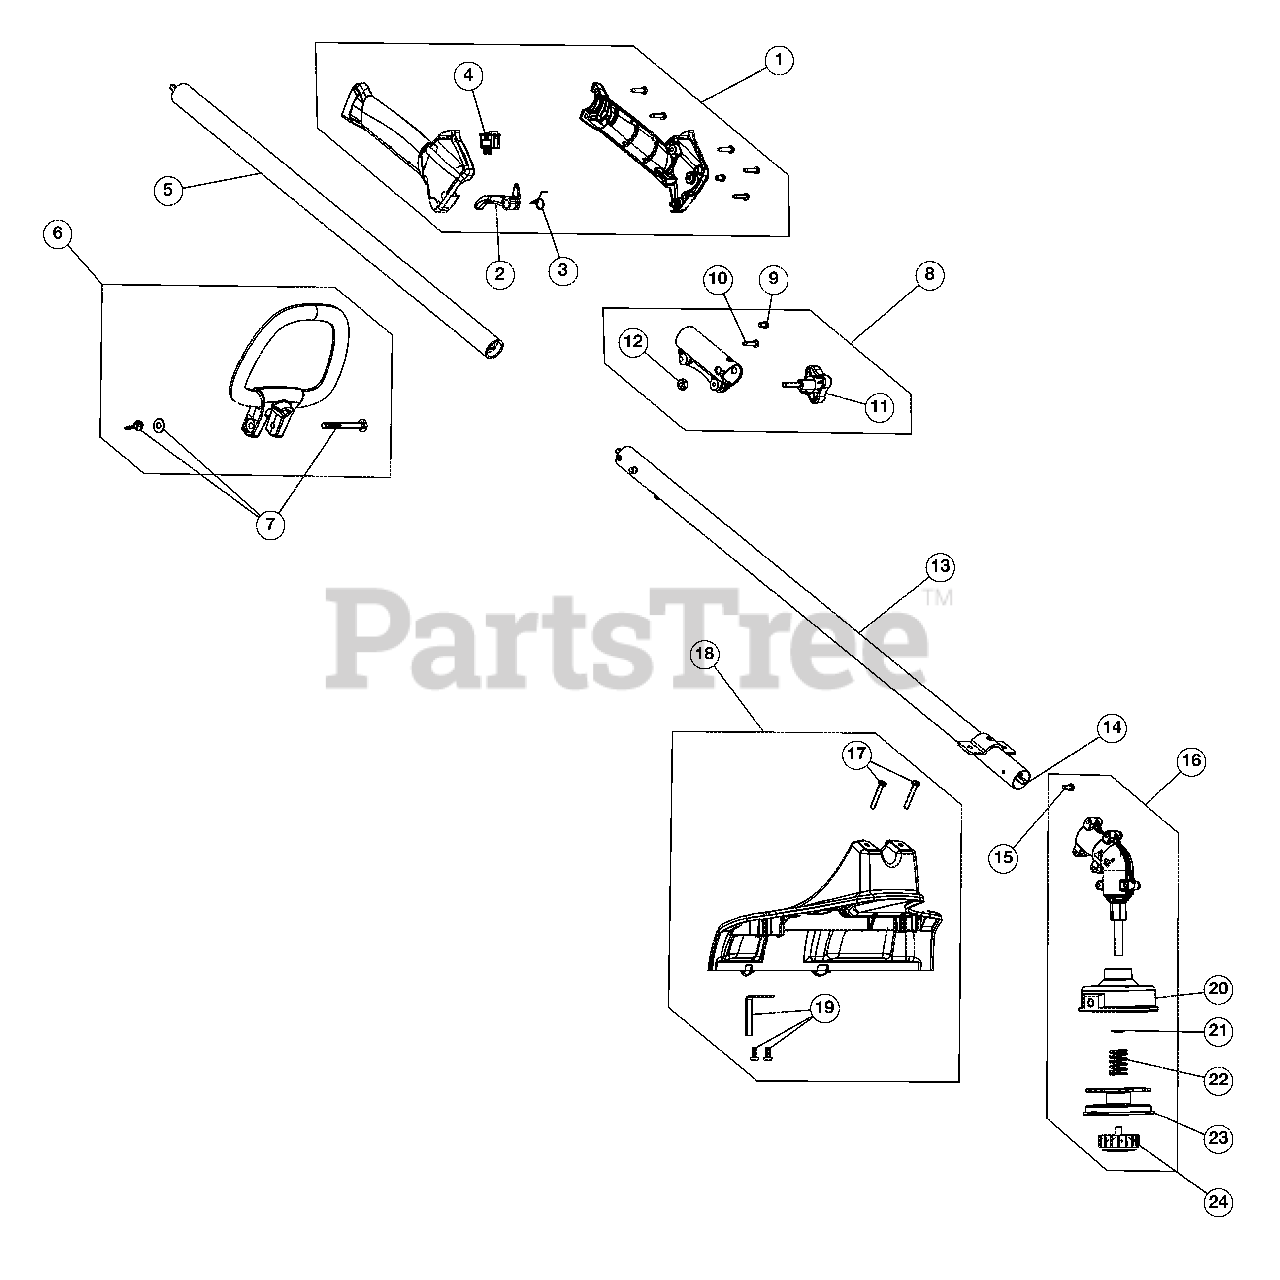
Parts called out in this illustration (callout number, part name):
1	Throttle Housing Assembly (Incl. 2-4)
2	Throttle Trigger
3	Throttle Trigger Spring
5	Upper Drive Shaft Housing Assembly
6	D-Handle Assembly (Incl. 7)
7	D-Handle Hardware
8	Split Boom Coupler (Incl. 9-12)
11	Adjustment Knob (Incl. 12)
12	Knob Retaining Nut
13	Lower Drive Shaft Housing Assembly
14	Lower Flexible Drive Shaft
15	Anti-Rotation Screw
16	Gear Box Assembly (Incl. 15 & 20-24)
17	Shield Mounting Screws
18	Shield Assembly (Incl. 17 & 19)
19	Blade Assembly
20	Outer Spool Assembly (Incl. 21)
21	Retainer
23	Inner Reel
24	Bump Knob Assembly
